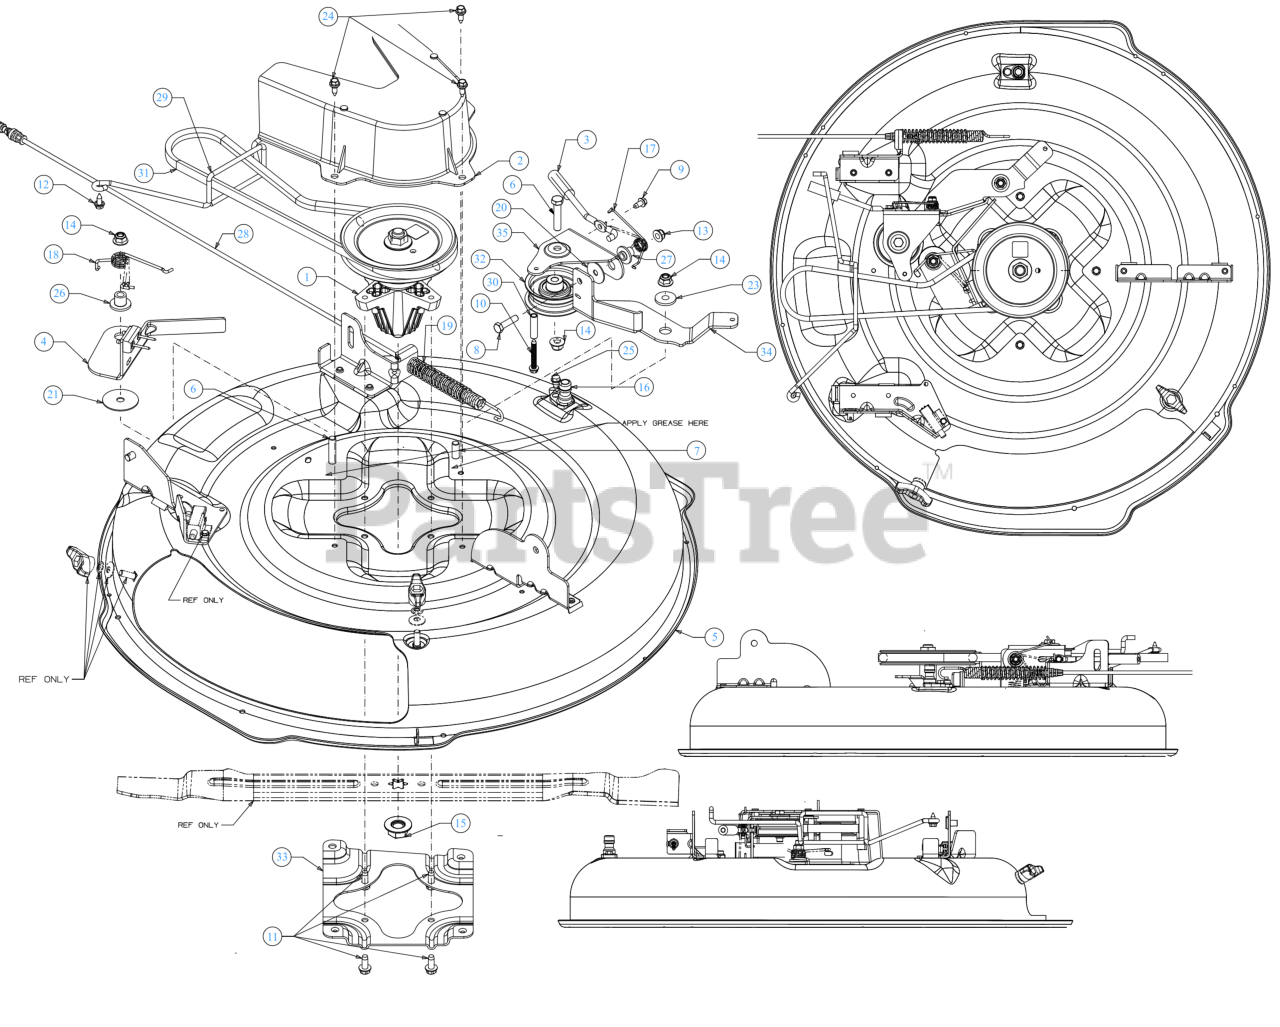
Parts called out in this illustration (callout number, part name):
1	SPINDLE ASSEMBLY
2	DECK BELT COVER ASSEMBLY
3	IDLER GUIDE ROD ASSEMBLY
4	BRAKE PTO BRACKET ASSEMBLY
5	30" DECK SHELL W/NOZZLE
6	HEX SCREW 3/8-16 x 1.75 GR5
7	SCREW 3/8-16 x 1 GR5
8	SCREW 5/16-18 x 1.5 LG
9	SCREW 1/4-20 X.500
10	SCREW 1/4-20 x 1.750
11	SCREW 5/16-18 x .875
12	SCREW 1/4-20X.625
13	FLANGE LOCK NUT 5/16-18
16	DECK WASH NOZZLE
17	TORSION SPRING PTO
18	TORSION SPRING BRAKE
20	FLAT WASHER 344X1.00
21	HUB CAP WASHER .406 x 1.92 x .060
23	SHOULDER SPACER
24	SHOULDER SCREW
25	SHOULDER SCREW 1/4-20X.50 19"PSH
26	DOUBLE SHOULDER SPACER
27	DOUBLE SHOULDER SPACER
29	DECK BELT KEEPER
30	SPACER:.260 x .372 x 1.420
31	V-BELT A SEC 43.5
32	FLAT IDLER PULLEY 2.75 OD
34	IDLER BRACKET FLOATING LOWER
